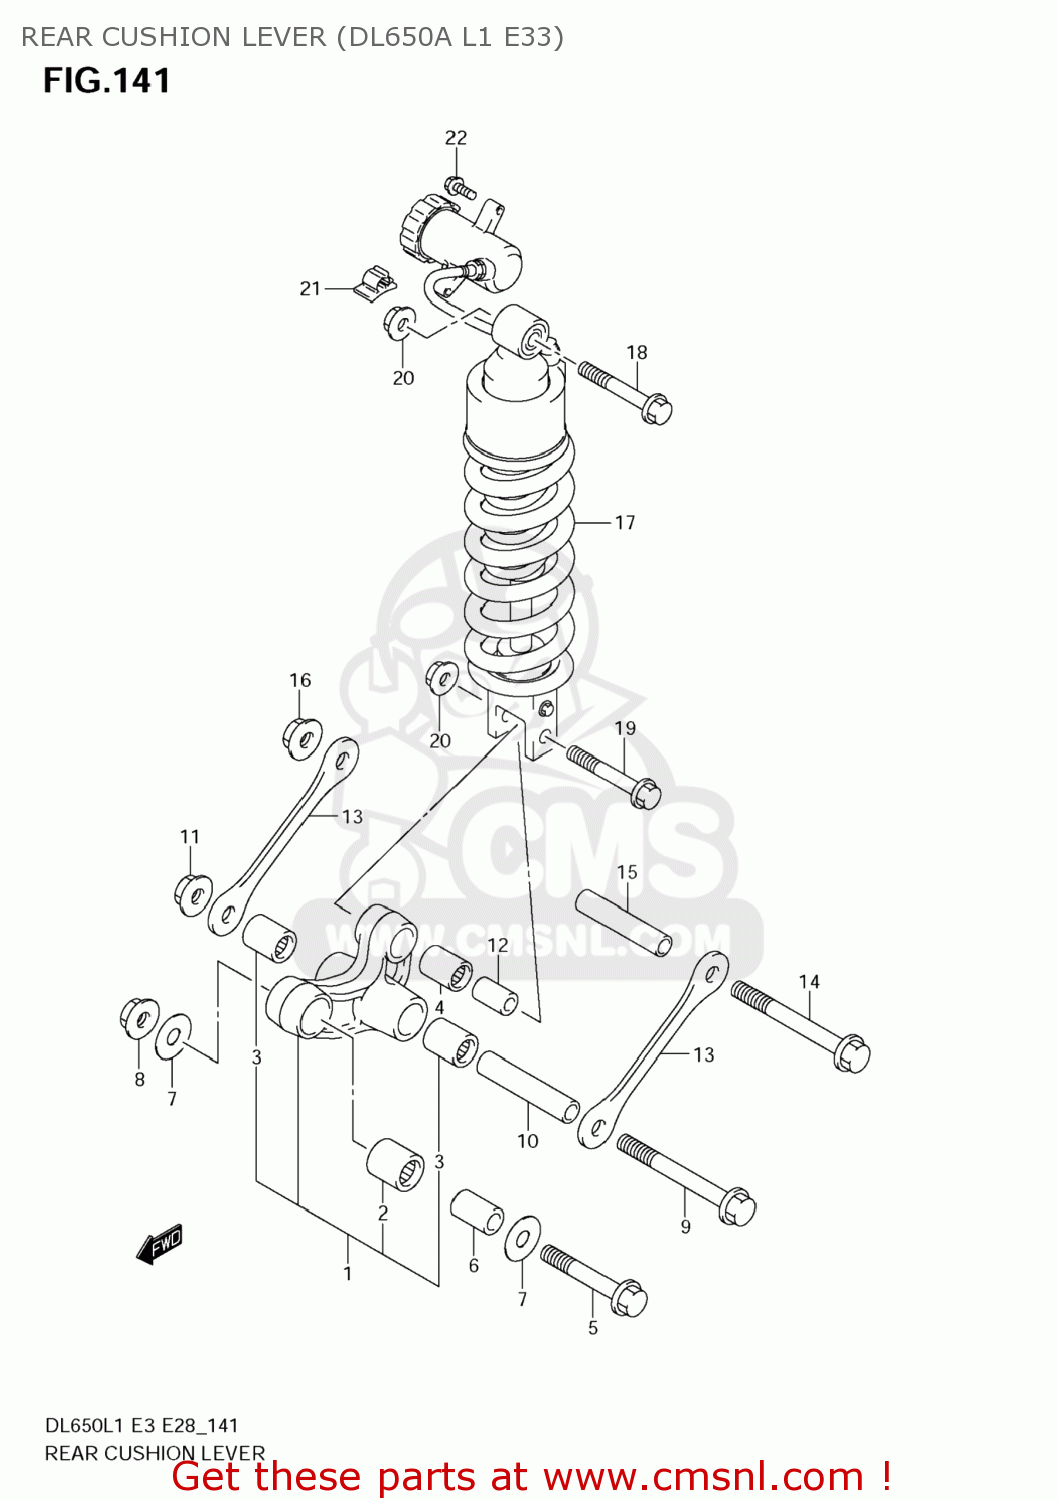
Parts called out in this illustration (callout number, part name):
1	LEVER SET,RR CUSHION
2	BEARING(20X27X30)
3	BEARING(17X24X25)
4	BEARING(17X24X26)
5	BOLT,RR CUSHION LEVER FR
6	SPACER,RR CUSHION LEVER FR
7	WASHER(12X34X1)
8	NUT
9	BOLT,RR CUSHION ROD
10	SPACER(12X17X85)
11	NUT
12	SPACER,RR CUSHION LEVER
13	ROD,RR CUSHION LEVER
14	BOLT,RR CUSHION ROD
15	SPACER(12X17X85)
16	NUT
17	ABSORBER ASSY,RR SHOCK(SILVER)
18	BOLT(10X70)
19	BOLT(10X55)
20	NUT
21	CLAMP
22	BOLT
